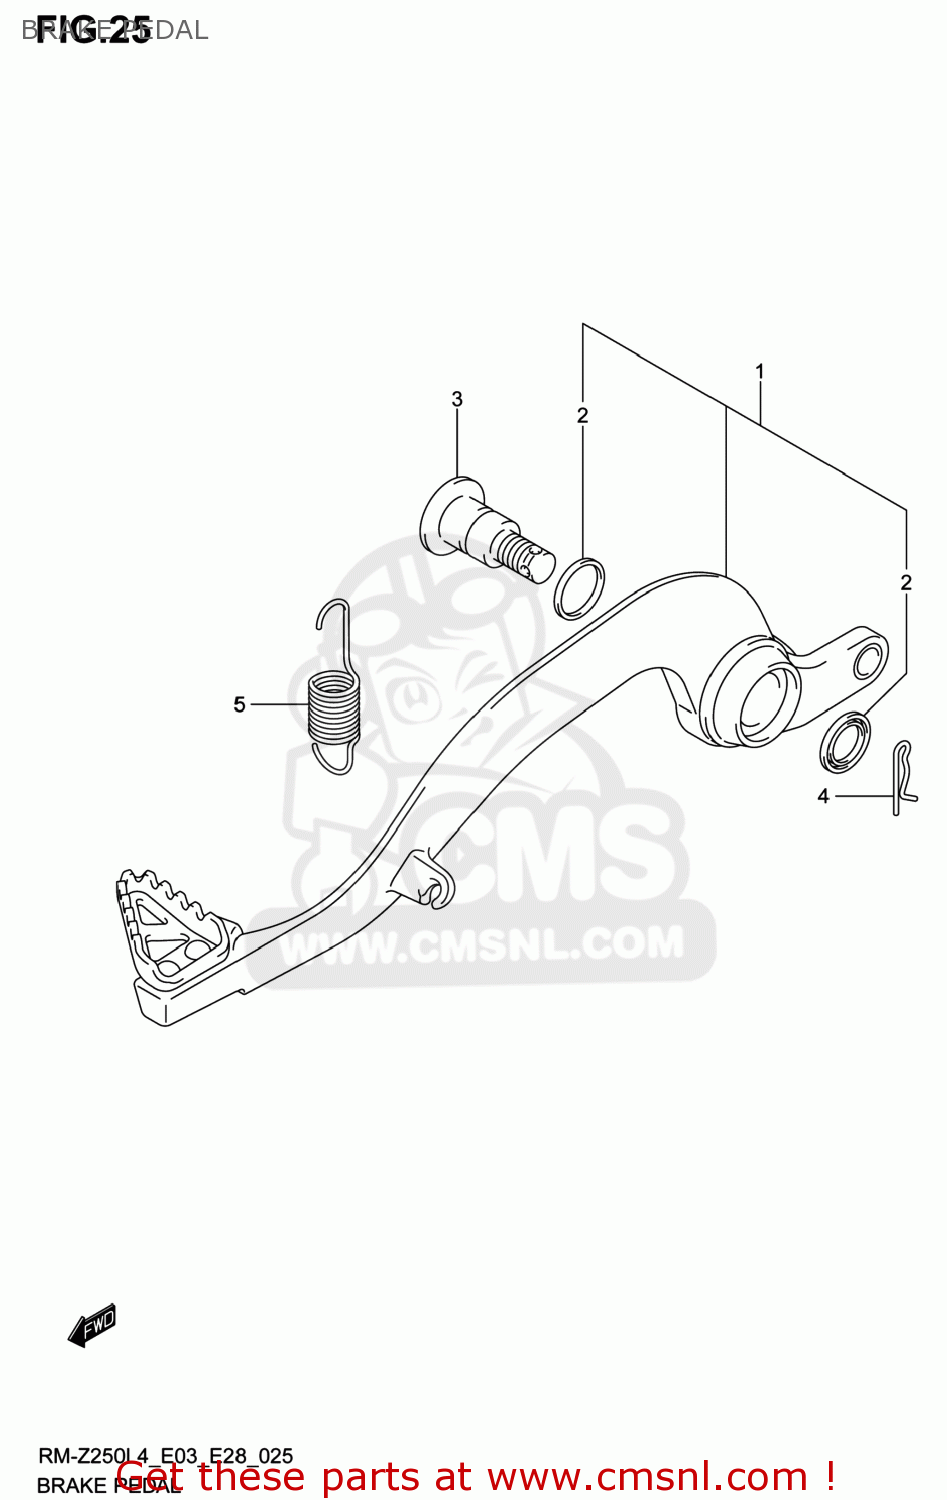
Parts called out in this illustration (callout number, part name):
1	PEDAL ASSY,BRAKE
2	SEAL,OIL(15X21X3)
3	SHAFT,BRAKE PEDAL
4	CLIP
5	SPRING
